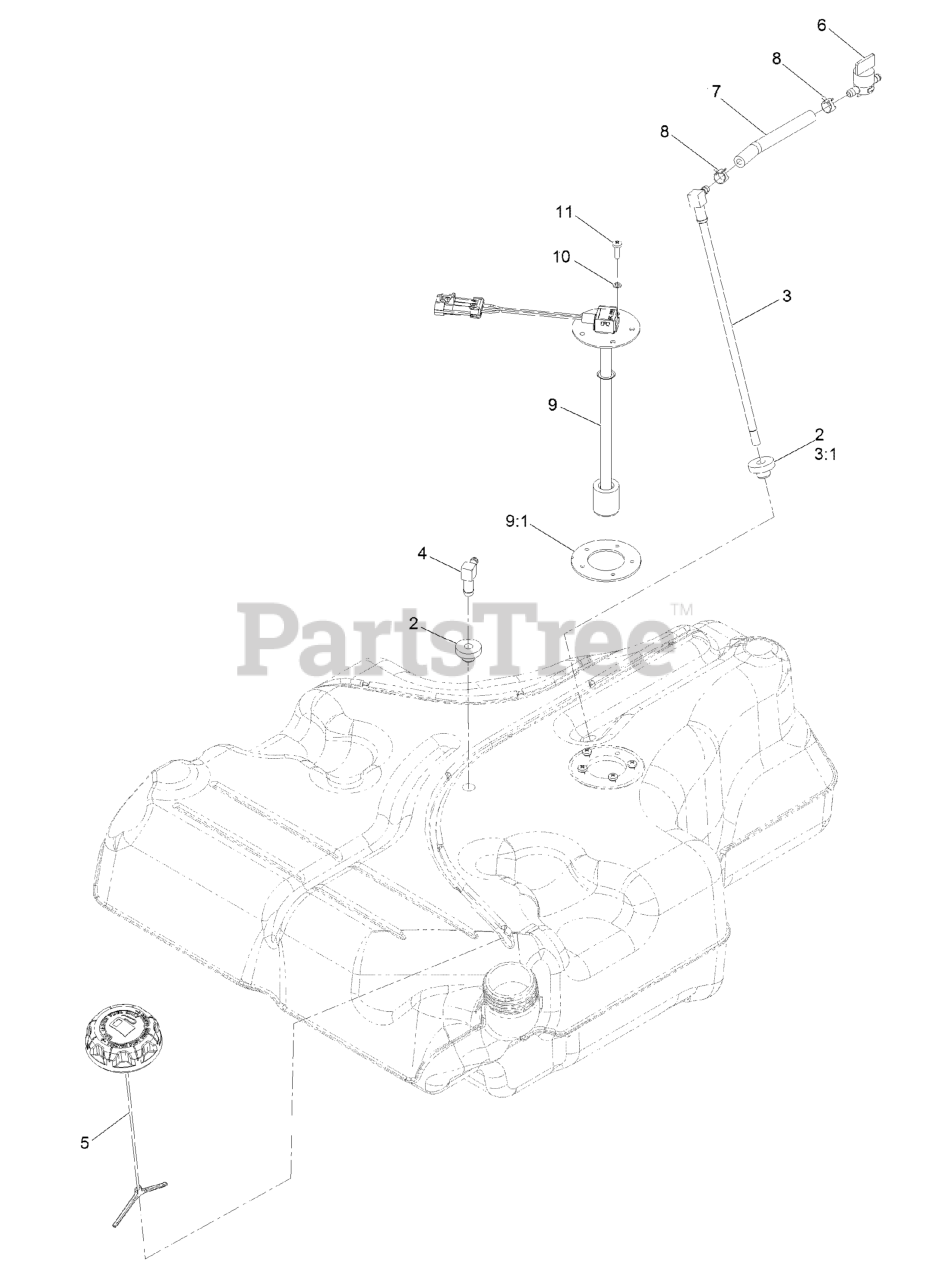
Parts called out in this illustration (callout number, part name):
2	BUSHING
3	FUEL LINE KIT (WITH GROMMET)
3:1	BUSHING
4	FITTING-90 ELBOW
5	CAP-FUEL, RATCHETING
6	VALVE-FUEL
7	HOSE-FUEL
8	CLAMP-HOSE
9	SENDER-LEVEL, FUEL (W/GAS
9:1	Gasket-Sender
10	WASHER-LOCK
11	SCREW-PPH
